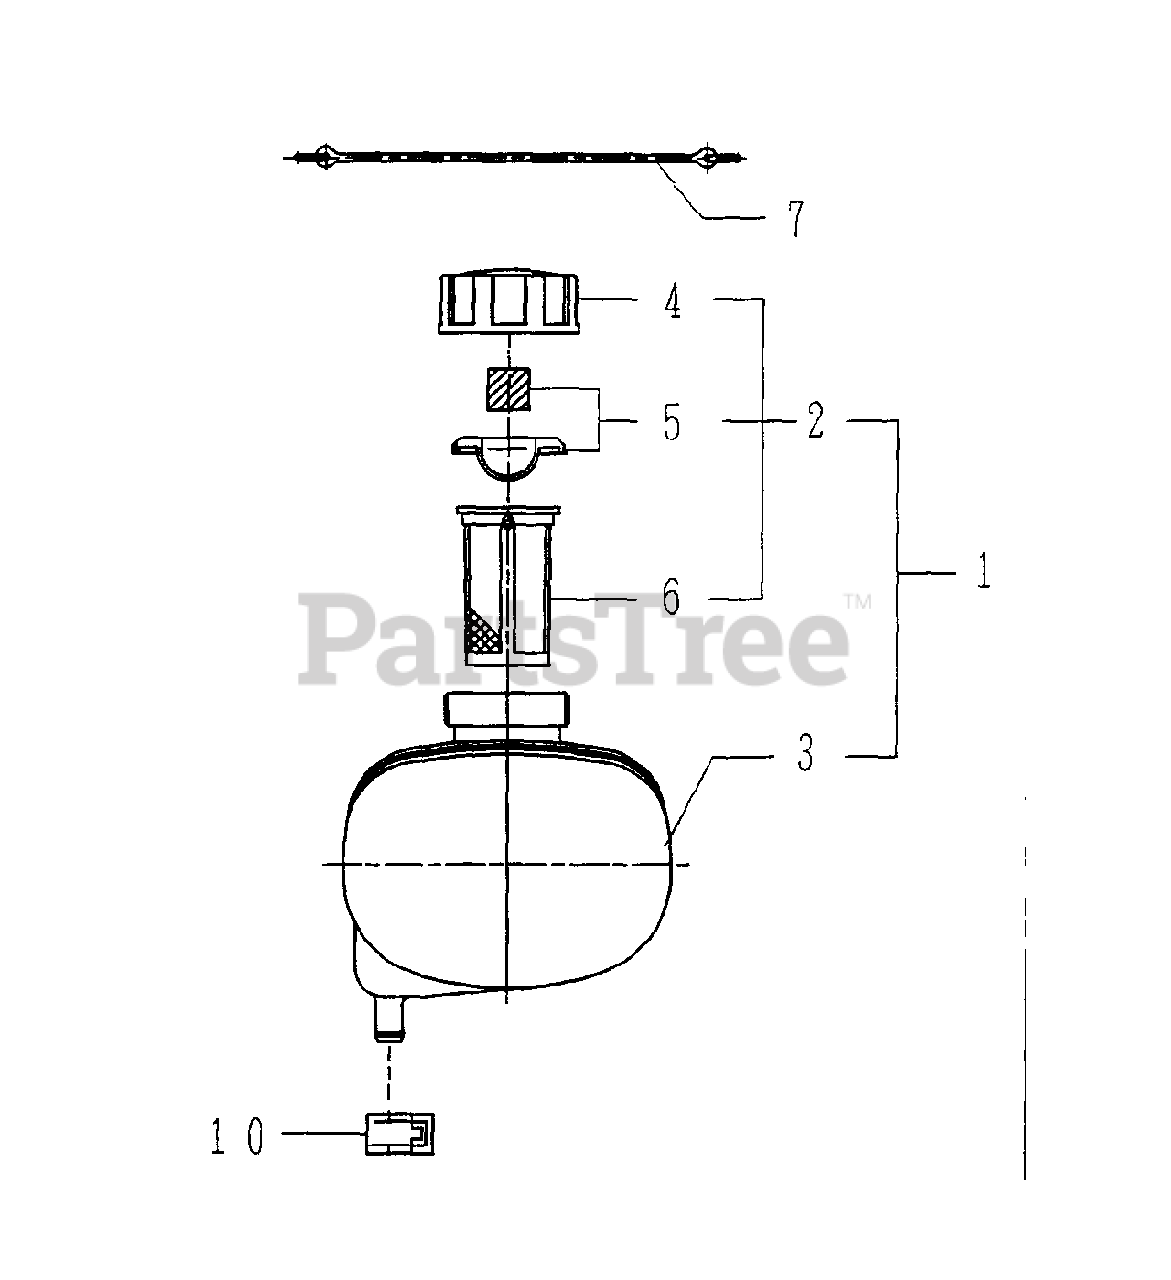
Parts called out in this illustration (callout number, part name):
1	TANK ASSY, FUEL
2	CAP ASSY, FUEL
3	TANK, FUEL
4	CAP, FUEL
5	VALVE, CHECK
6	STRAINER
7	BAND, FUEL TANK
10	CLAMP
